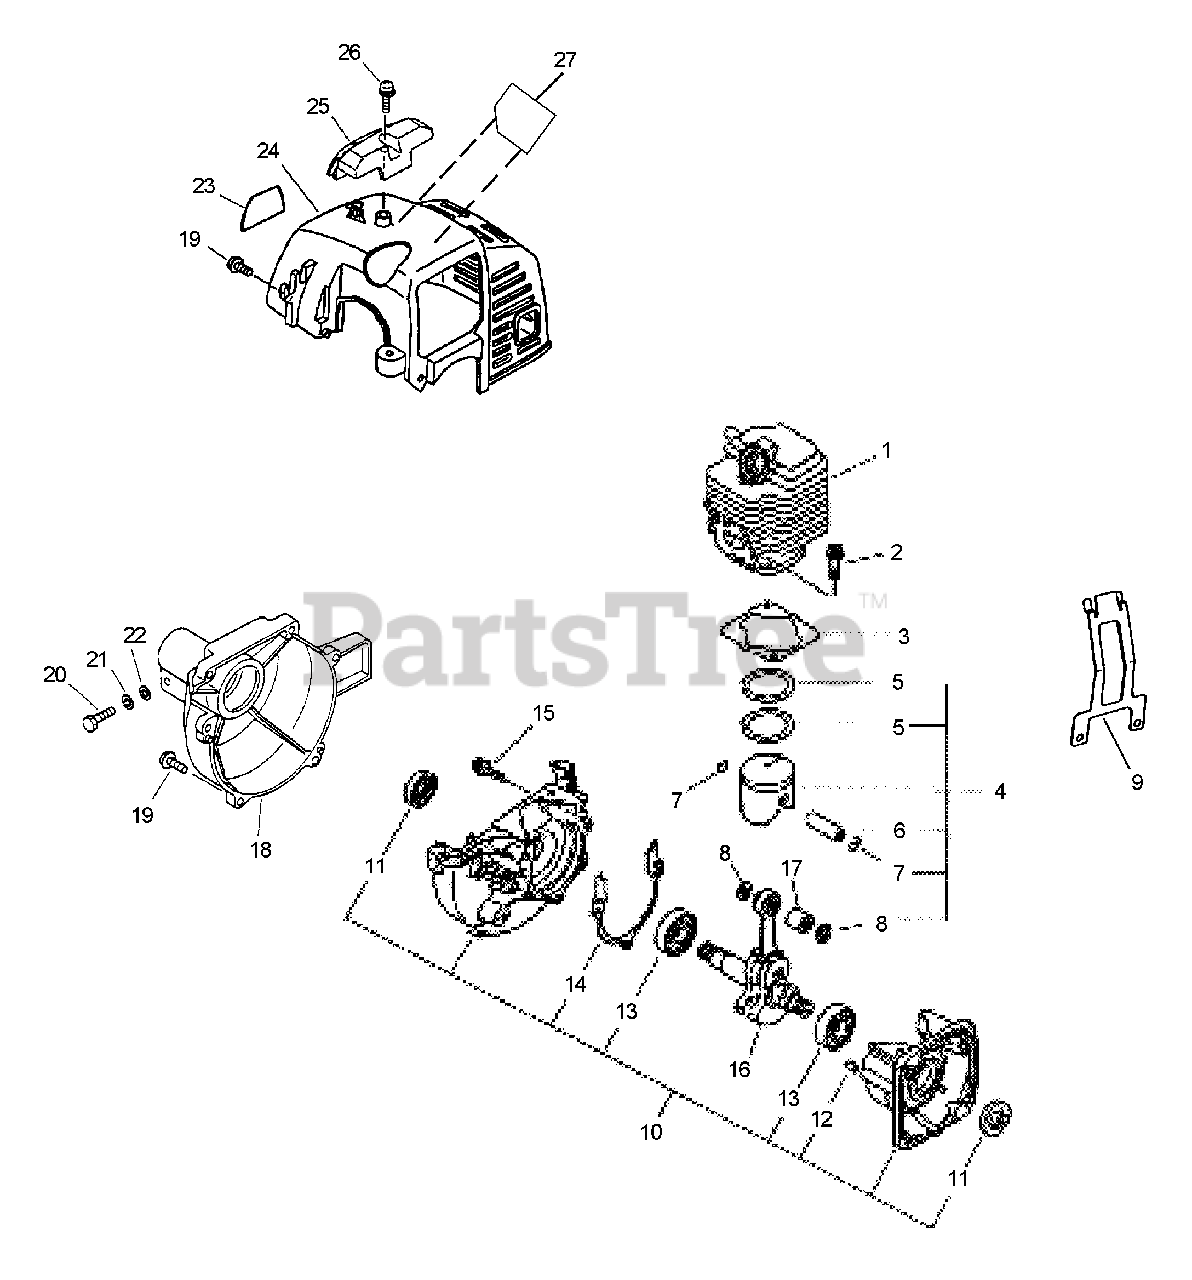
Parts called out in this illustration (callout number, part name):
1	CYLINDER
2	BOLT 5×22
3	GASKET, CYLINDER
4	PISTON KIT
5	RING, PISTON
6	PIN, PISTON 8
7	RING, SNAP
8	WASHER, THRUST
9	GUARD, ENGINE
10	CRANKCASE ASSY
11	SEAL, OIL 12
12	PIN, LOCATING 4
13	BEARING, BALL - 6201 C3
14	GASKET, CRANKCASE
15	BOLT 5×28
16	CRANKSHAFT ASSY
17	BEARING, NEEDLE
18	CASE, FAN
19	BOLT 4×16
20	BOLT 5×25
21	WASHER, SPRING 5
22	WASHER, FLAT 5.5×10×0.8
23	LABEL - MODEL
24	COVER, ENGINE - ORANGE
25	GUARD, TOP - BLACK
26	SCREW 5×16
27	LABEL, CAUTION
